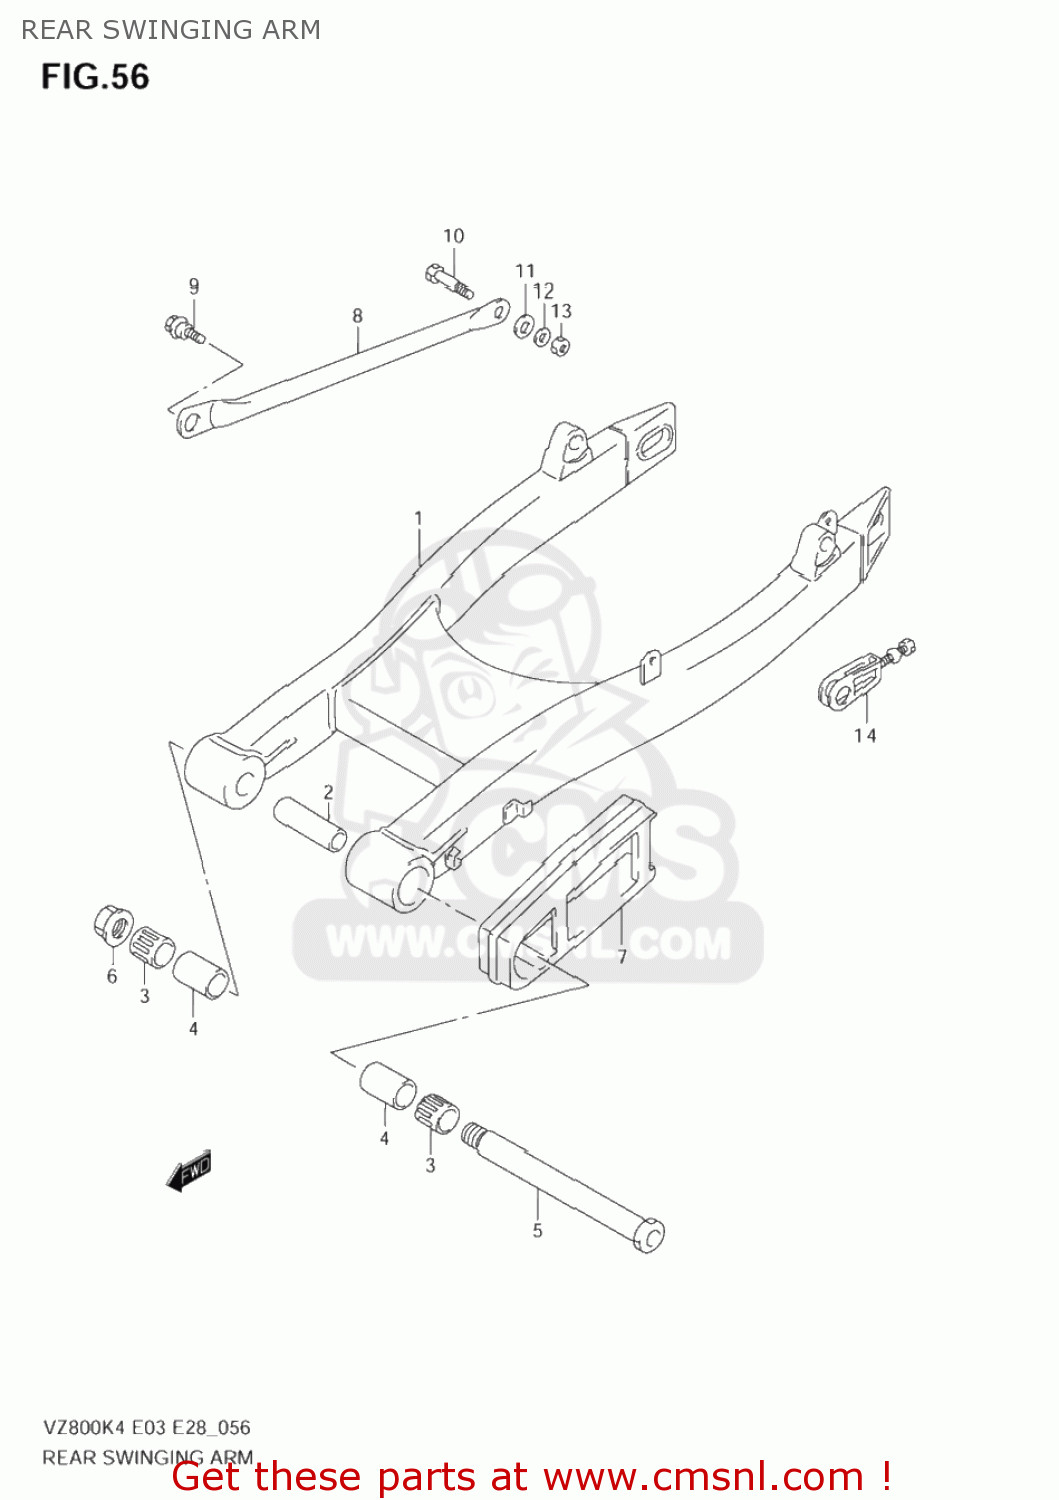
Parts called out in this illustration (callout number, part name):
1	SWINGINGARM,RR
2	SPACER,RR SWGARM PIVOT CTR
3	BEARING(25X33X35)
4	SPACER,RR SWGARM PIVOT
5	SHAFT,RR SWINGINGARM PIVOT
6	NUT ,18MM
7	BUFFER,CHAIN TOUCH DEFENSE
8	TORQUE LINK,RR
9	BOLT(10X30)
10	BOLT(10X41)
11	CUSHION
12	WASHER (10X20X2.3)
13	NUT
14	ADJUSTER ASSY,CHAIN
